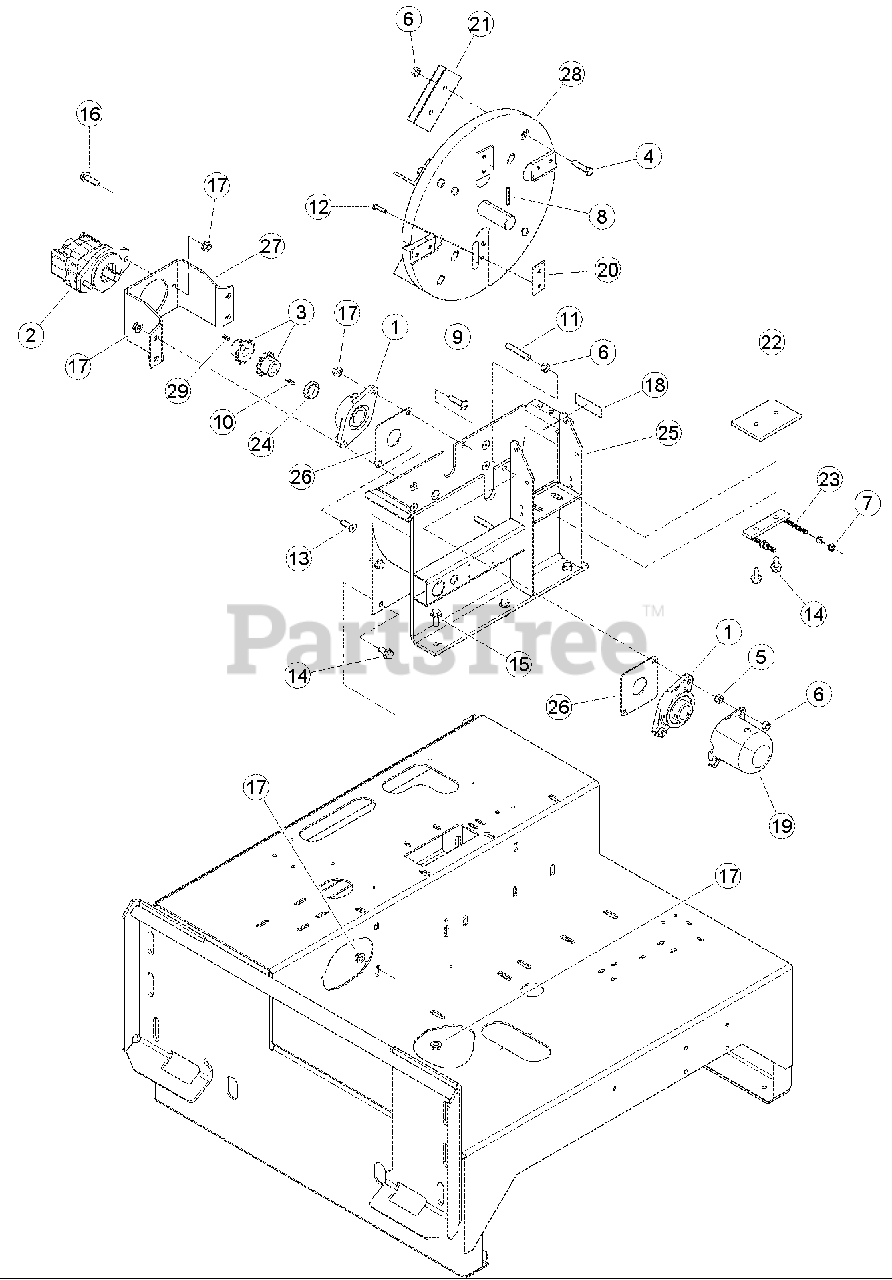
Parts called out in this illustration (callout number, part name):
1	BEARING, 1-1/2" 2-BOLT SET SCREW
2	MOTOR, 1.24 CU. IN. HYD
3	COUPLER, CHAIN 7/8" I.D.
4	BOLT, 1/2 X 2 HEX HD GR5 ZP
5	NUT, 1/2 HEX NC ZP
6	NUT, 1/2 CENTERLOCK GRB ZP
7	NUT, 3/8 SERR FLANGE NC ZP
8	SPRINGPIN, 1/4 X 2 LONG
9	BOLT, 1/2 X 2 CRG GR5 ZP
10	KEY, 3/16 SQUARE X 1 LONG
11	STUD, 1/2-13 X 3 LG B7 ZP
12	BOLT, 5/16 X 1-1/4 HEX HD GR8 PATCH
13	SCREW, 1/2 X 1-1/2 FLT HD SKT
14	BOLT, 1/2 X 1 SERR FLANGE
15	BOLT, 1/2 X 1-1/4 SERR FLANGE
16	BOLT, 1/2 X 1-1/2 SERR FLANGE
17	NUT, 1/2 SERR FLANGE NC ZP
18	DECAL, SERIAL NUMBER
19	CAP, LARGE SHAFT
20	KIT, CHIPPER BLADE
21	ANGLE, CHIPPER THROWER
22	ANVIL, 4 INCH CHIPPER
23	WELDMENT, BLOCK ADJUSTOR
24	SPACER, 1-3/4 X 7/16 X .120
25	WELDMENT, BOTTOM CHIPPER HOUSING
26	PLATE, BEARING
27	MOUNT, ROTOR MOTOR
28	WELDMENT, ROTOR (BOBCAT)
29	KEY, 3/16 X 1/4 X 3/4 STEP
